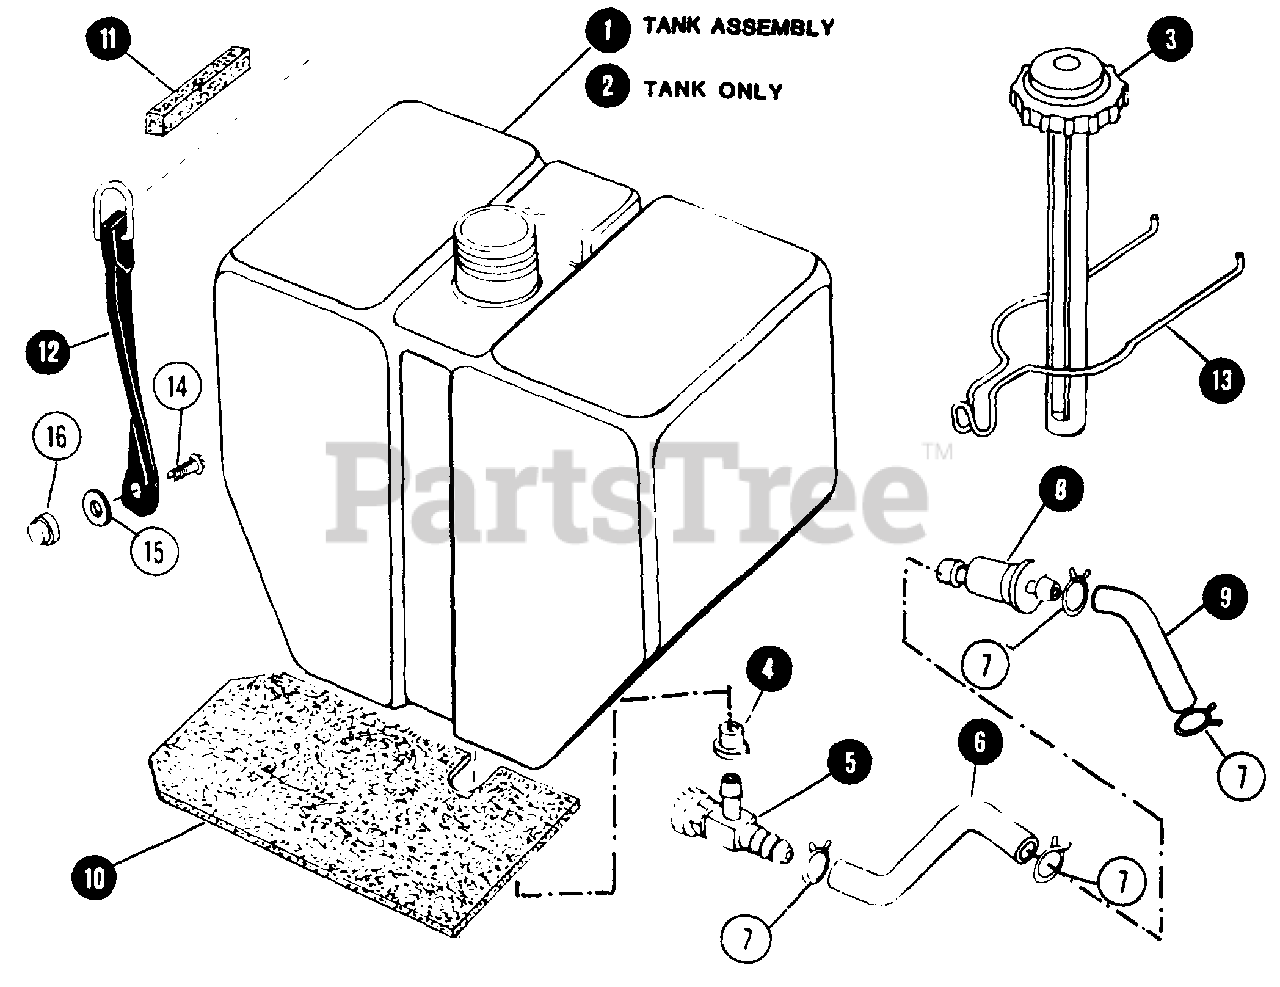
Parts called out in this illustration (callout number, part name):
1	FUEL TANK ASSEMBLY
2	TANK, FUEL
3	CAP & GAUGE ASSEMBLY
4	BUSHING, VALVE TO TANK
5	VALVE, FUEL SHUT-OFF
6	LINE FUEL - 5" LONG
7	CLAMP, FUEL LINE
8	FILTER, IN-LINE FUEL
9	LINE, FUEL - 3" LONG
10	PAD, FUEL TANK- LOWER
11	PAD FUEL TANK- UPPER
12	RETAINER STRAP - ASSEMBLY
13	CLAMP, TANK RETAINER
14	SCREW, #10C x 1-1/4 ROUND HEAD
15	WASHER, 7/32 x 1 x 5/64"
16	RING, TANK RETAINER
